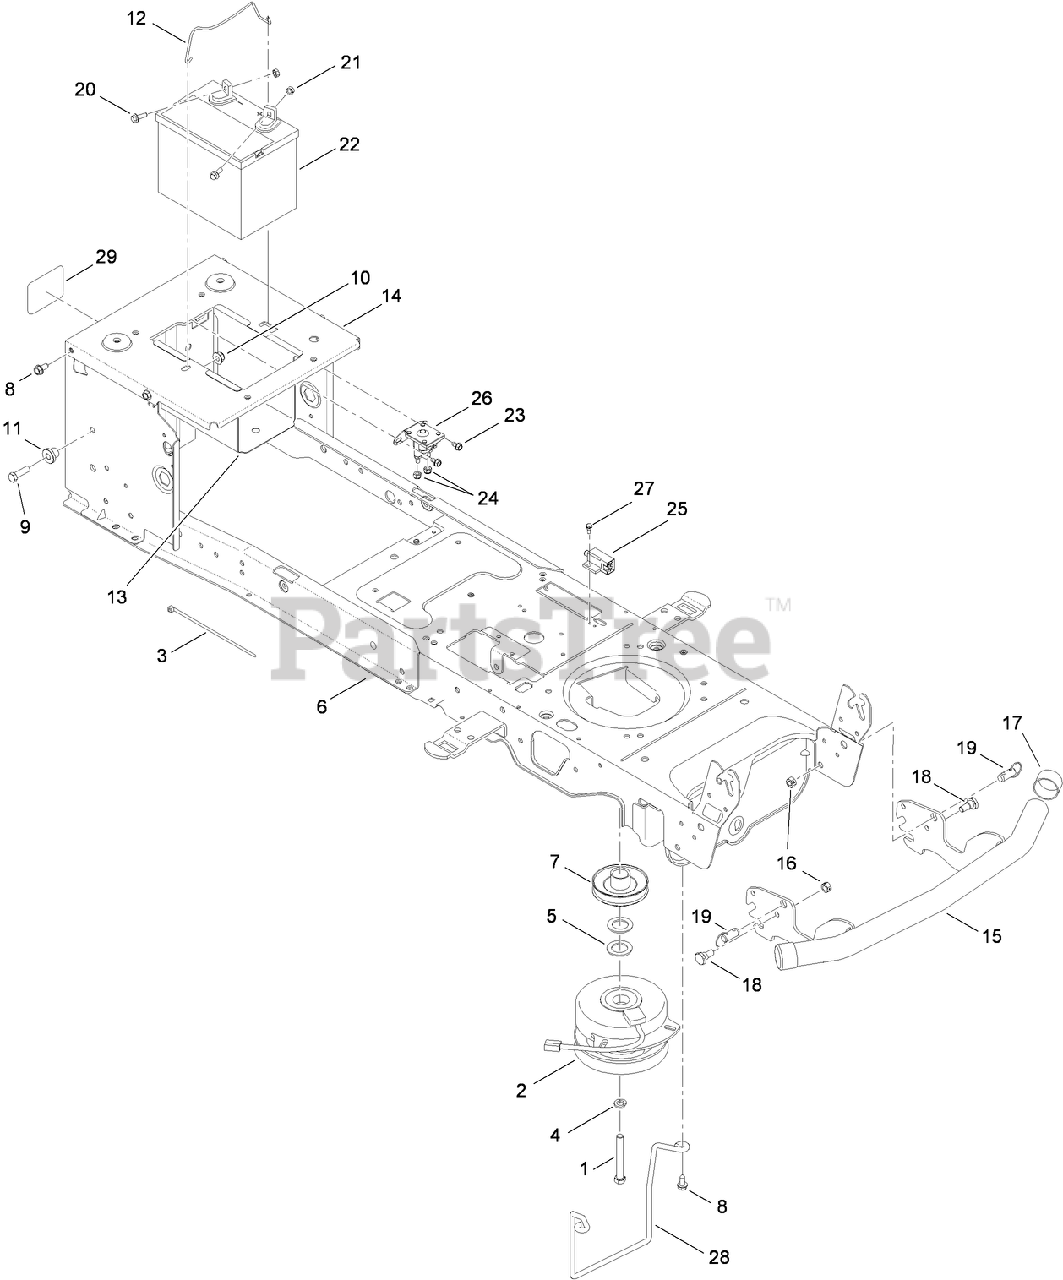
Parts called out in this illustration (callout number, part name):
1	SCREW-HH
2	CLUTCH-ELECTRIC
3	TIE-CABLE
4	WASHER-LOCK
5	WASHER-FLAT
6	LOWER FRAME ASM
7	PULLEY-ENGINE
8	SCREW-TAP
9	SCREW-HH
10	NUT-LOCK, FLANGE
11	SPACER-SHOULDER
12	ROD-HOLDDOWN, BATTERY
13	TRAY-BATTERY
14	BRACKET-FRAME, SEAT
15	BUMPER-UNIVERSAL
16	NUT-LOCK
17	CAP-HUB
18	BOLT-SHOULDER
19	PIN-RELEASE, QUICK
21	NUT-SEMS
22	BATTERY-245, CCA (DRY FLAT TOP)
23	SCREW-TAP
24	NUT-LOCK, FLANGE
25	SWITCH-INTERLOCK, NO/NC
26	SOLENOID-12V, 2 POST 2 Tab
27	BOLT-SHOULDER
28	ROD-KEEPER, BELT
29	DECAL-RELEASE, HYDRO
